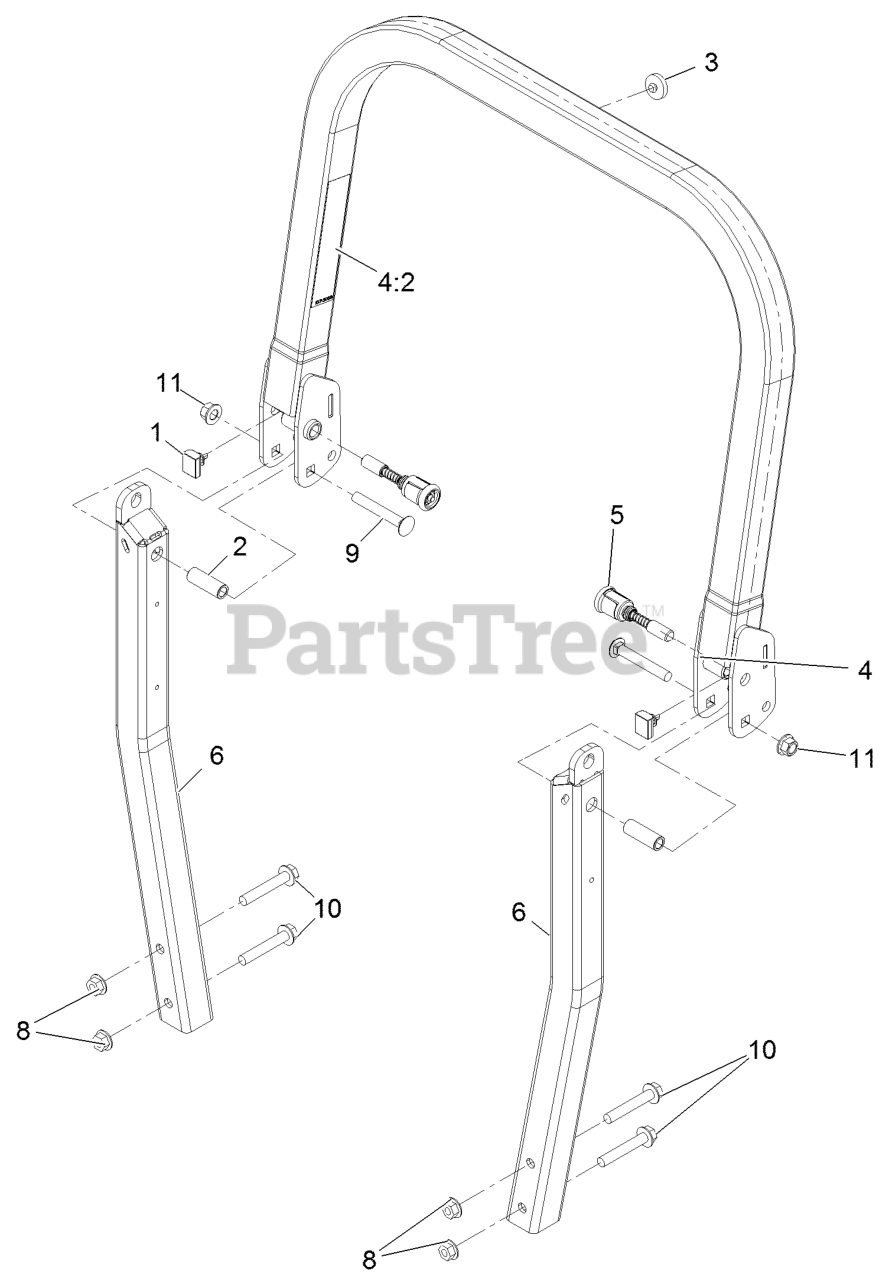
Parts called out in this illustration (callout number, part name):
1	BUMPER-ROPS
3	BUMPER-PUSH-IN, RUBBER
4	UPPER ROPS ASM
4:2	DECAL-WARNING
5	PIN-SPRING
6	NUT-HHF
8	SCREW-CARR
9	SCREW-HF
10	Nut-Lock 1/2-13
